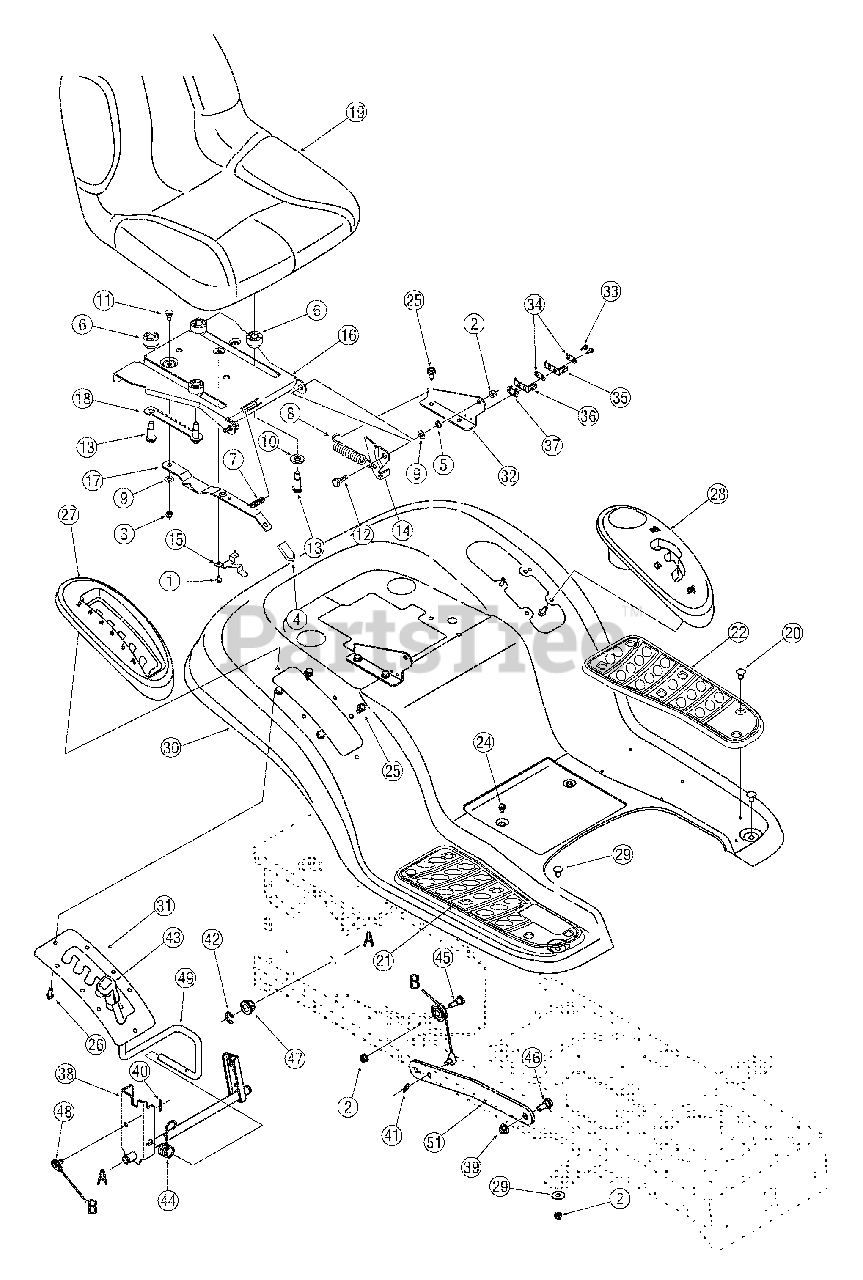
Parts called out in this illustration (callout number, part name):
1	Screw, #10-16 x .375
2	Nut, Flange Lock, 5/16-18, Gr F, Nylon
3	Nut, Flange Lock, 1/4-20
4	Seat Adjuster Grip
5	Nut, Speed, .3125 ID
6	Spacer
7	Compression Spring, .41 x 1.5
8	Spring, Extension, .84 Dia. x 4.6
9	Wash, Flat, .344 x .688 x .065
10	Wash, Flat, .531x 1.062 x.134
11	Screw, Shoulder, .340 x .285,1/4-20
12	Screw, Shoulder, .437 x .268, 5/16-18
13	Screw, Shoulder, .50 x .925, 3/8-16
14	Seat Bracket, Lift
15	Seat Stop
18	Seat Adjustment Selector
19	High Back Seat, Black
20	Ratchet Clip
21	RH Foot Pad, Rubber
22	LH Foot Pad, Rubber
23	Bolt, Carriage, 5/16-18, .62, Gr1
24	Screw, 1/4-20, 0.500
25	Screw, 5/16-12, 0.750
26	Screw, 1/4-15, 0.750
27	Cover, Lift Lever
28	Cover, w/ Cup Holder
29	Washer, Flat, .344 x 1.0 x .063
33	Screw, #8-18 x .50
34	Plate, Insulator
35	Spring Switch, Inner
36	Spring Switch, Outer
37	Plate, Insulator Boss
39	Nut, Flange Lock, 3/8-16, Gr F, Nylon
40	Pin, Cotter, .072 Dia. x 1.13
41	Pin, Cotter, 3/32, 1.0
42	Ring, E Type, .625 Dia.
43	Grip, Handle, 1/2
44	Spring, Torsion
45	Screw, 5/16-18 x .620 Gr2
46	Screw, Shoulder, .50 x .27, 3/8-16
47	Bearing, Hex Flange
48	Cable, Lift, 16.16
49	Handle, Lift
